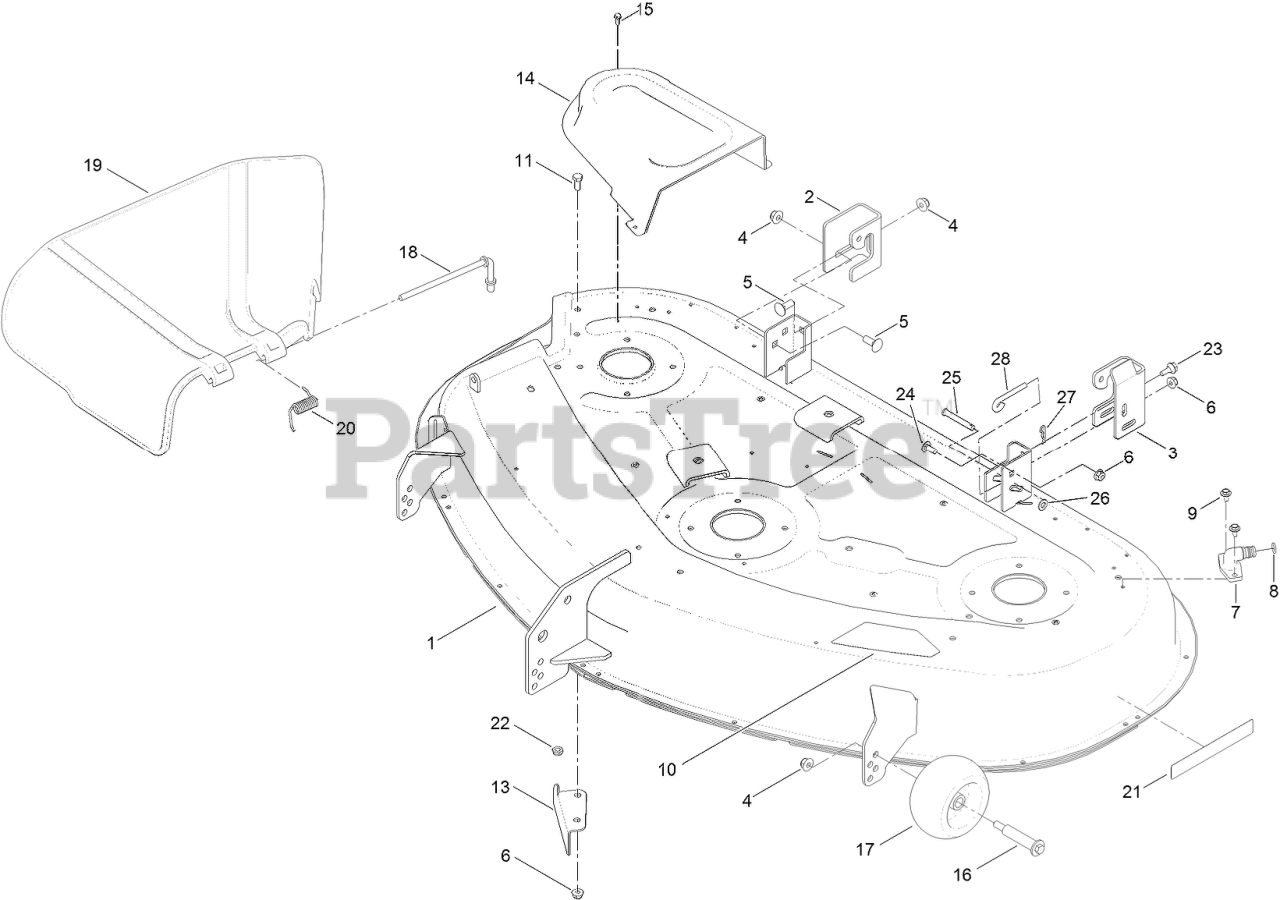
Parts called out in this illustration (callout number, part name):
1	50 INCH DECK AND DECAL ASM
2	BRACKET-HANGER, RH
3	BRACKET-HANGER, LH
4	NUT-HF, NI
5	BOLT-CARR
6	NUT-HF, NI
7	FITTING-WASHOUT
8	O-RING
9	SCREW-HHFTF
11	SCREW-HH
13	BAFFLE-CUTOFF
14	COVER-BELT
15	SCREW-TAPTITE
16	BOLT-SHOULDER
17	ROLLER-SCALP, ANTI
18	ROD-PIVOT
19	DEFLECTOR
20	SPRING-TORSION
21	DECAL-RECYCLER
22	NUT-LOCK, NI
23	SCREW-SHOULDER, HHF
24	SCREW-CARR
25	PIN-CLEVIS
26	WASHER-PLAIN
27	PIN-COTTER
28	ROD-LEVEL, DECK
